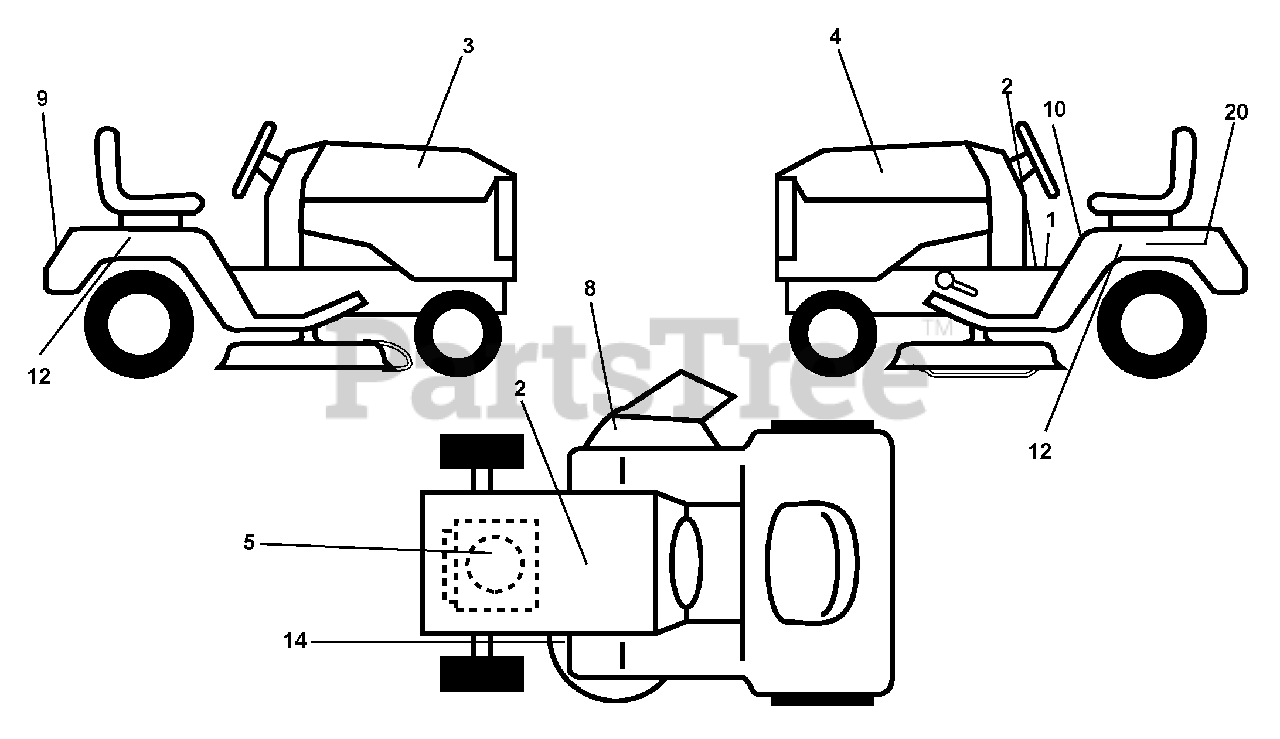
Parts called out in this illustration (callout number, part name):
1	Decal Oper. Step Thru E/F
2	Decal Battery
3	Decal Hood LH
4	Decal Hood RH
5	Decal HP Engine
8	Decal Warning Multi-Languages
9	Decal Fender Husq
10	Decal Fender Danger E/F
12	Decal Fender Auto Husq Radius
14	Decal V-Belt Schematic
